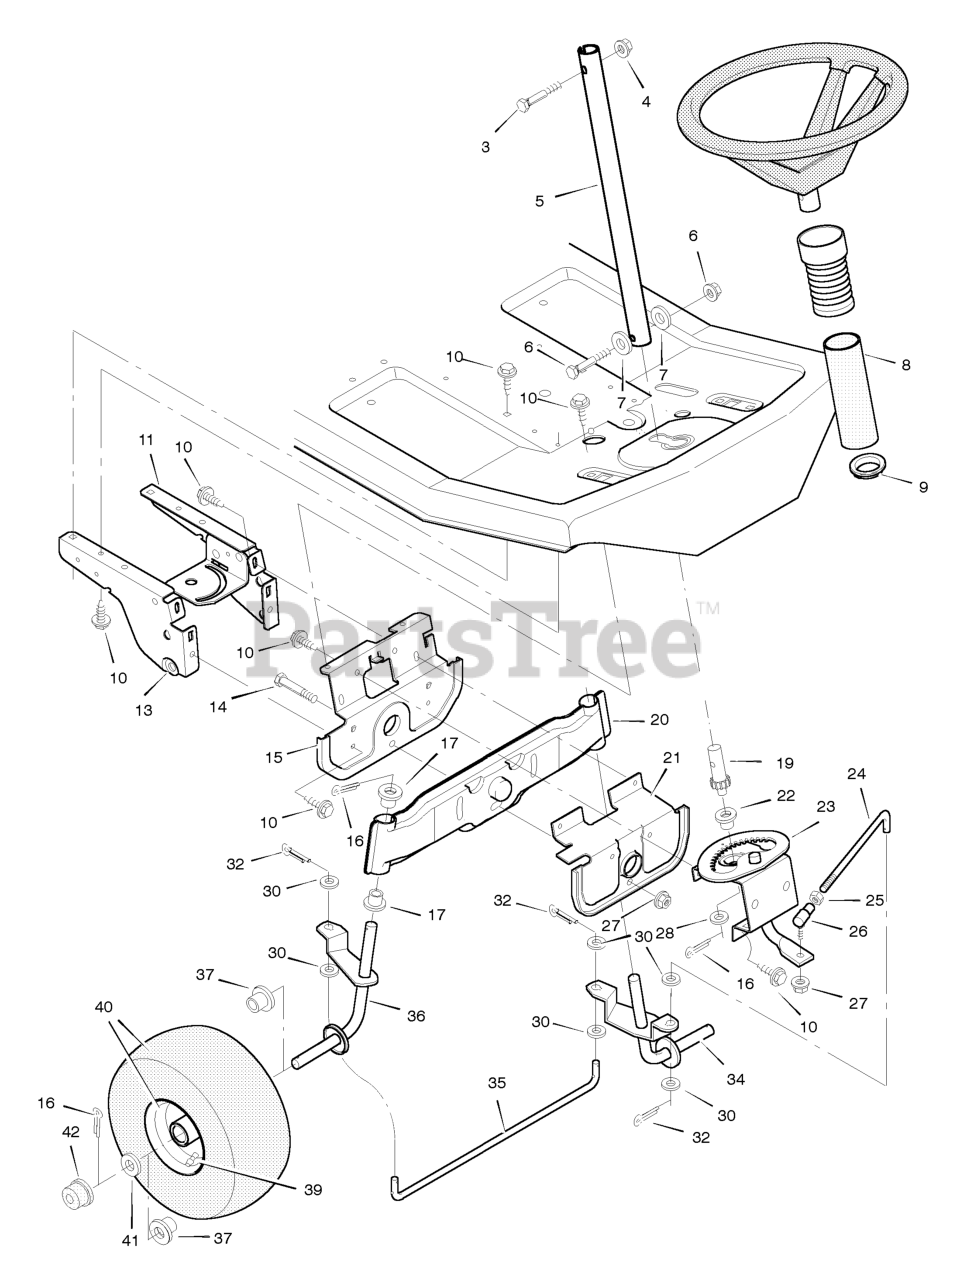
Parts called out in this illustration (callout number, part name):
1	Steering Wheel
2	Bellows
3	Bolt, Hex
4	Locknut, Flange
5	Post, Steering
6	Nut, Hex
7	Washer
8	Cover, Steering Post
9	Bearing
11	Plate, Left Suspension
13	Plate, Right Suspension
14	Bolt, Hex
15	Support, Front Axle
16	Pin, Cotter
17	Bearing, Spindle
19	Gear, Pinion
20	Axle Assembly, Front
21	Hanger Assembly, Front Axle
22	Bearing
23	Sector Assembly
24	Rod, Drag Link
25	Ball Joint, Steering
26	Nut, Hex
27	Locknut, Flange
28	Washer
30	Washer
32	Pin, Cotter
34	Spindle Assembly, Left
35	Rod, Tie
36	Spindle Assembly, Right
37	Bearing, Wheel
39	Valve Stem
40	Wheel & Tire Assembly
42	Cap, Hub
